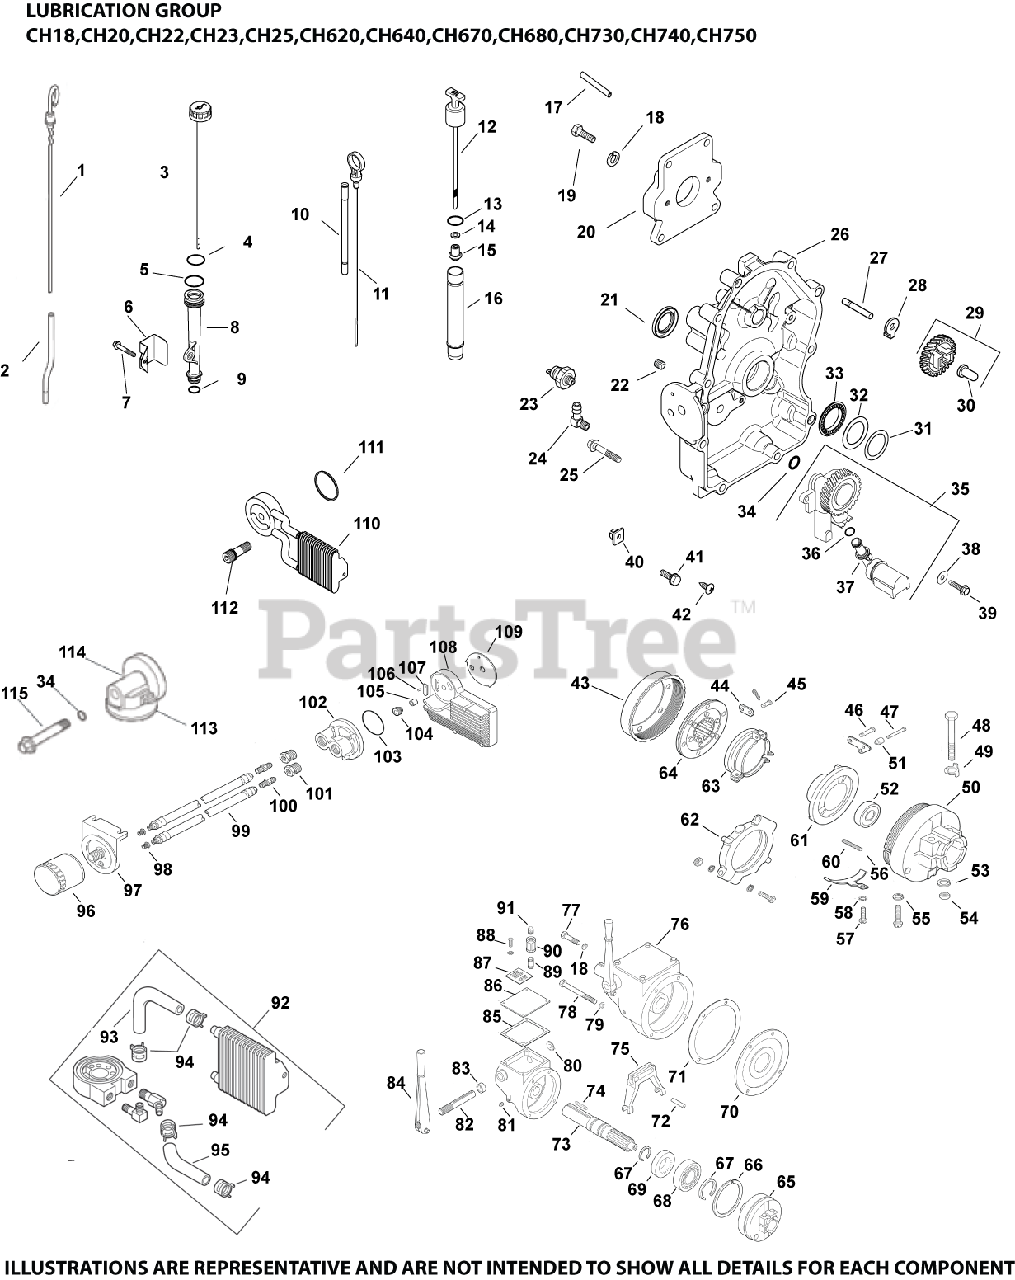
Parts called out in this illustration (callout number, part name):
10	KIT, DIPSTICK/DIPSTICK TUBES
21	SEAL, OIL
23	SENSOR, OIL PSI
24	CONNECTOR, 90 DEG. HOSE
25	SCREW, FLG M8X1.25X45
25	SCREW - DISCONTINUED
26	PLATE, CLOSURE & BEARING USE 24 009 227-S
27	SHAFT, GOVERNOR GEAR
28	TAB, LOCKING
29	KIT, GOVERNOR GEAR W/PIN
30	PIN, GOVERNOR REGULATING
35	KIT, OIL PUMP ASSEMBLY
36	O-RING, OIL PICK-UP
37	PICK-UP, OIL
38	WASHER, FLAT 6 MM
39	SCREW,FLG THD FRM M6X1.0X25-(#25086395S)
96	OIL FILTER
112	NIPPLE, OIL FILTER
